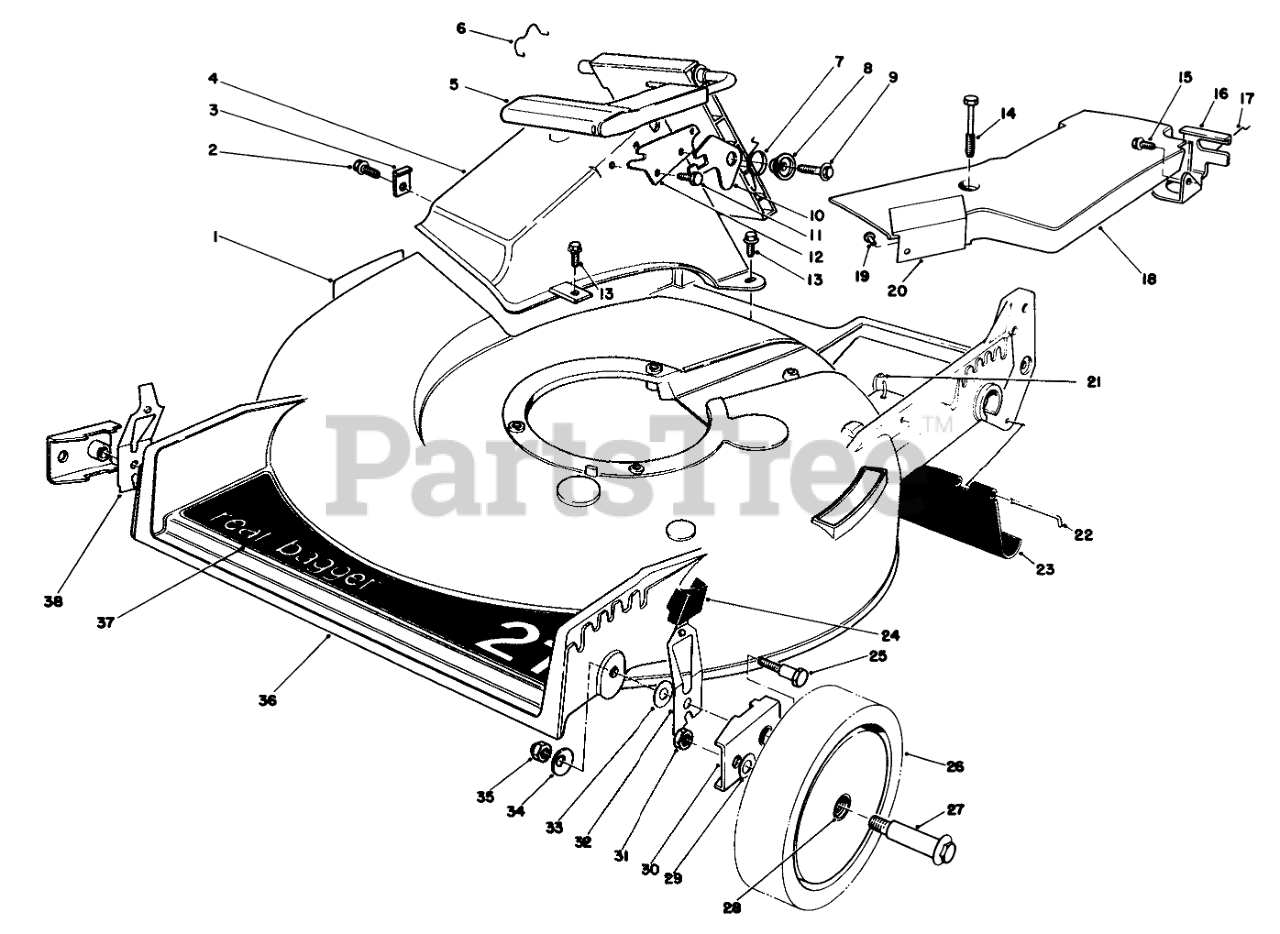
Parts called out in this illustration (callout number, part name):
1	DECAL-DANGER
2	SCREW
3	TUNNEL CLIP
4	Tunnel Discharge
5	Discharge Door Assembly
6	DOOR RET SPRING
7	TORSION SPRING
8	DOOR SPACER
9	SCREW-HWH
10	SAFETY LATCH
11	SCREW-PLASTITE
12	DOOR LATCH PLATE
13	SCREW-HWH
14	SCREW-HHFTF
15	SCREW-HWHTF
16	Bracket-Traction Adj.
17	RETAINER-CABLE
18	Belt Cover Assembly (Incl. Ref. #19 & 20)
19	RIVET-HEAD, FLAT
20	HEAT SHIELD
21	TIE-CABLE
22	ROD-SHIELD
23	SHIELD-TRAILING
24	KNOB-ARM
25	PIVOT SCREW
26	Wheel & Tire Assembly (Incl. Ref. #30)
27	BOLT-WHEEL
28	BUSHING
29	WASHER
30	HP PIVOT ARM ASM
31	Nut
32	L. HP SPRING ARM ASM
33	WASHER-PIVOT
34	WASHER-BELLEVILLE
35	NUT-LOCK, NI
36	Housing (Incl. Ref. #1)
37	DECK DECAL
38	R HP SPRING ARM ASM
